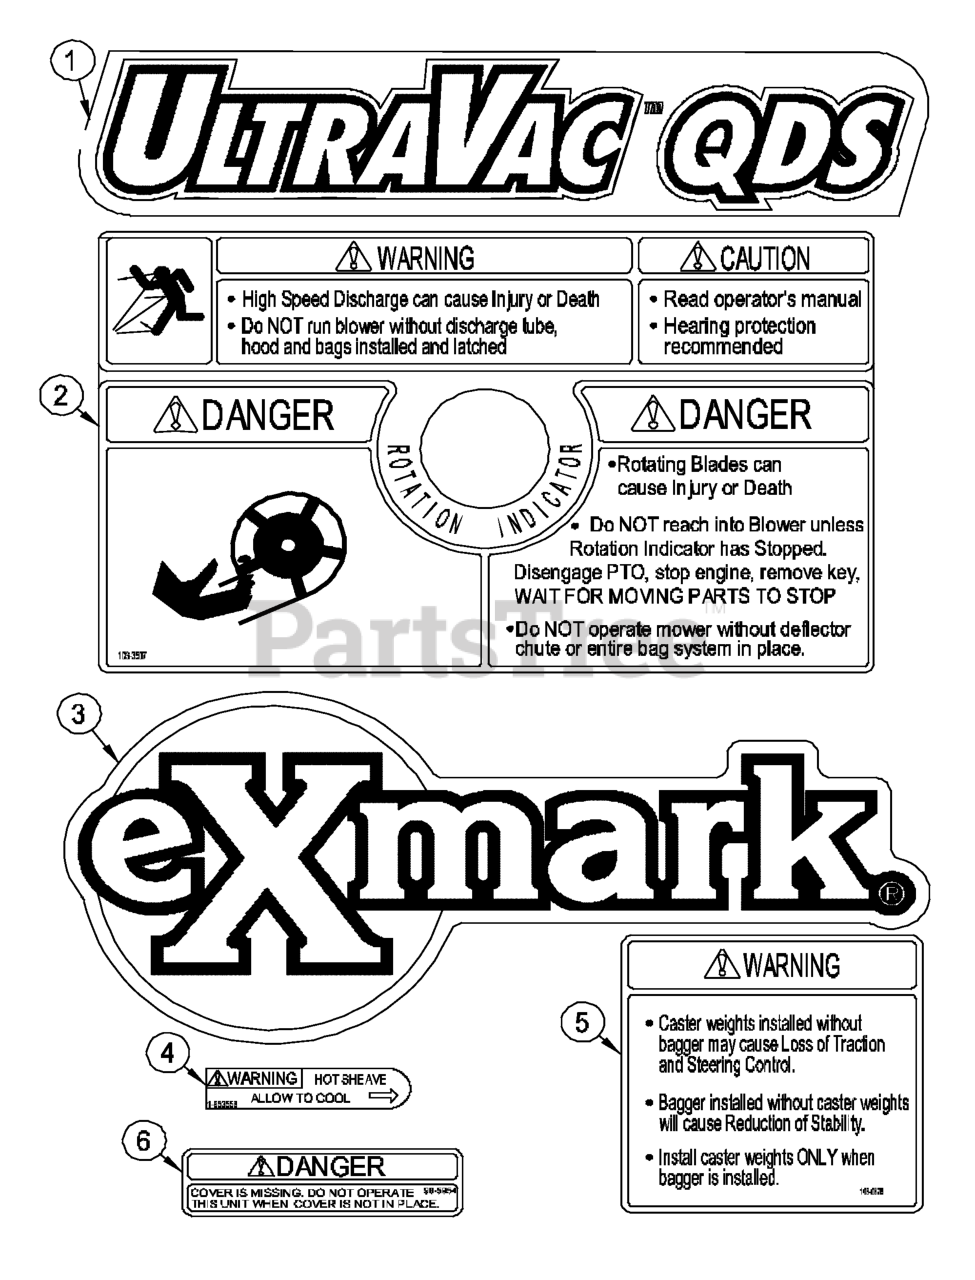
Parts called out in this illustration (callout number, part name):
1	DECAL, ULTRAVAC QDS
3	DECAL, EXMARK
4	DECAL-WARNING
6	DECAL-COVER, MISSING
